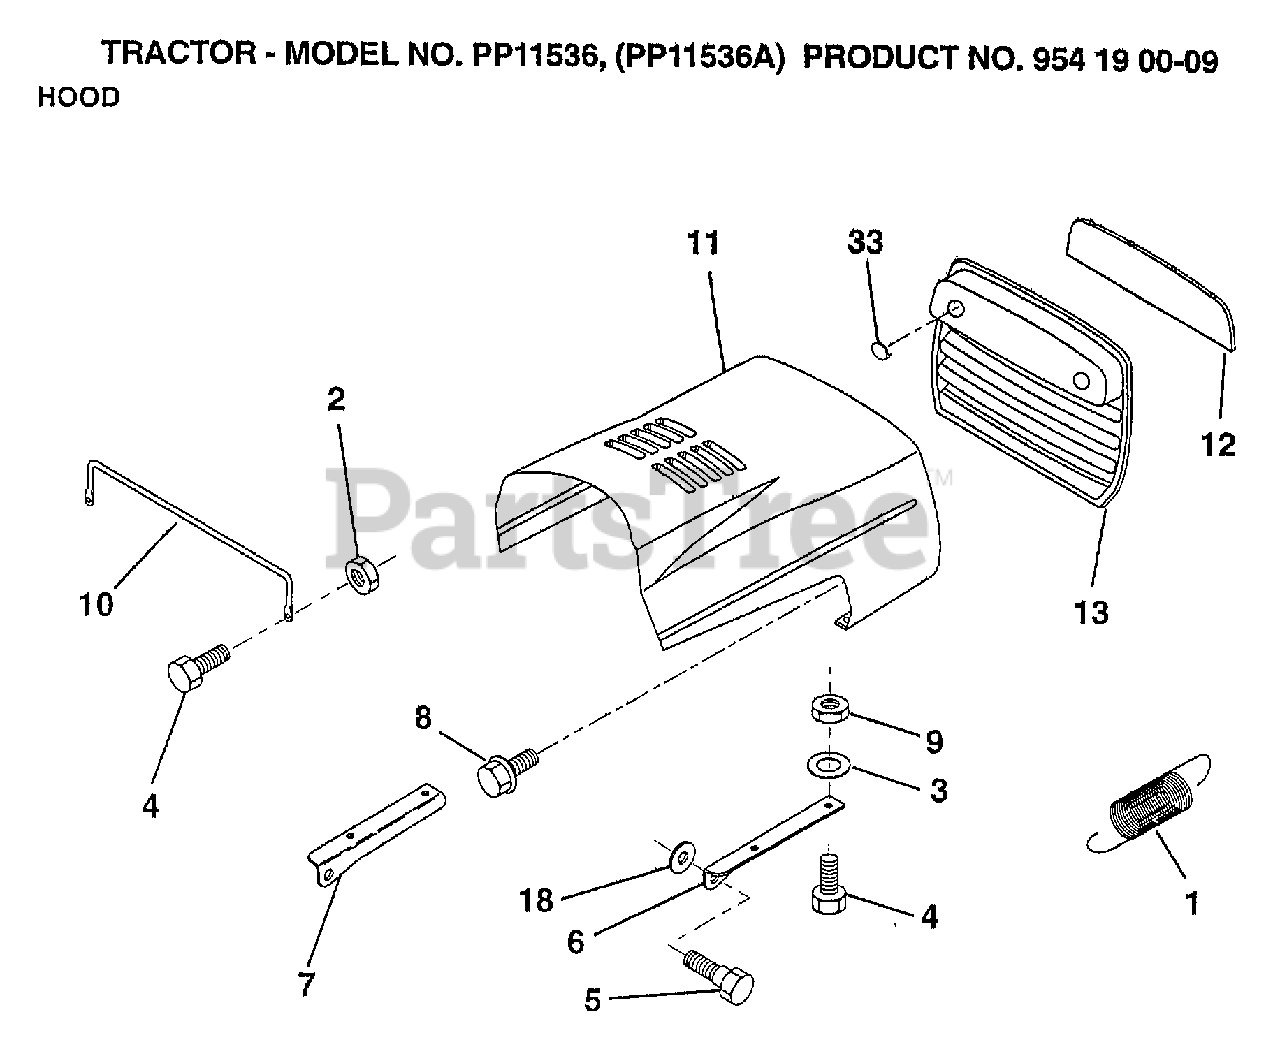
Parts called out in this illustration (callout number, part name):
1	EXT SPRING
2	NUT HXKEP 1/4X20
3	WASHER
5	BOLT.SHLD.5/16-18
6	BRKT HOOD RH
7	BRKT HOOD LH
8	SCREW SLTD HXHD
9	NUT
10	"BRACE,HOOD"
12	LENS
13	GRILL
18	WASHER
